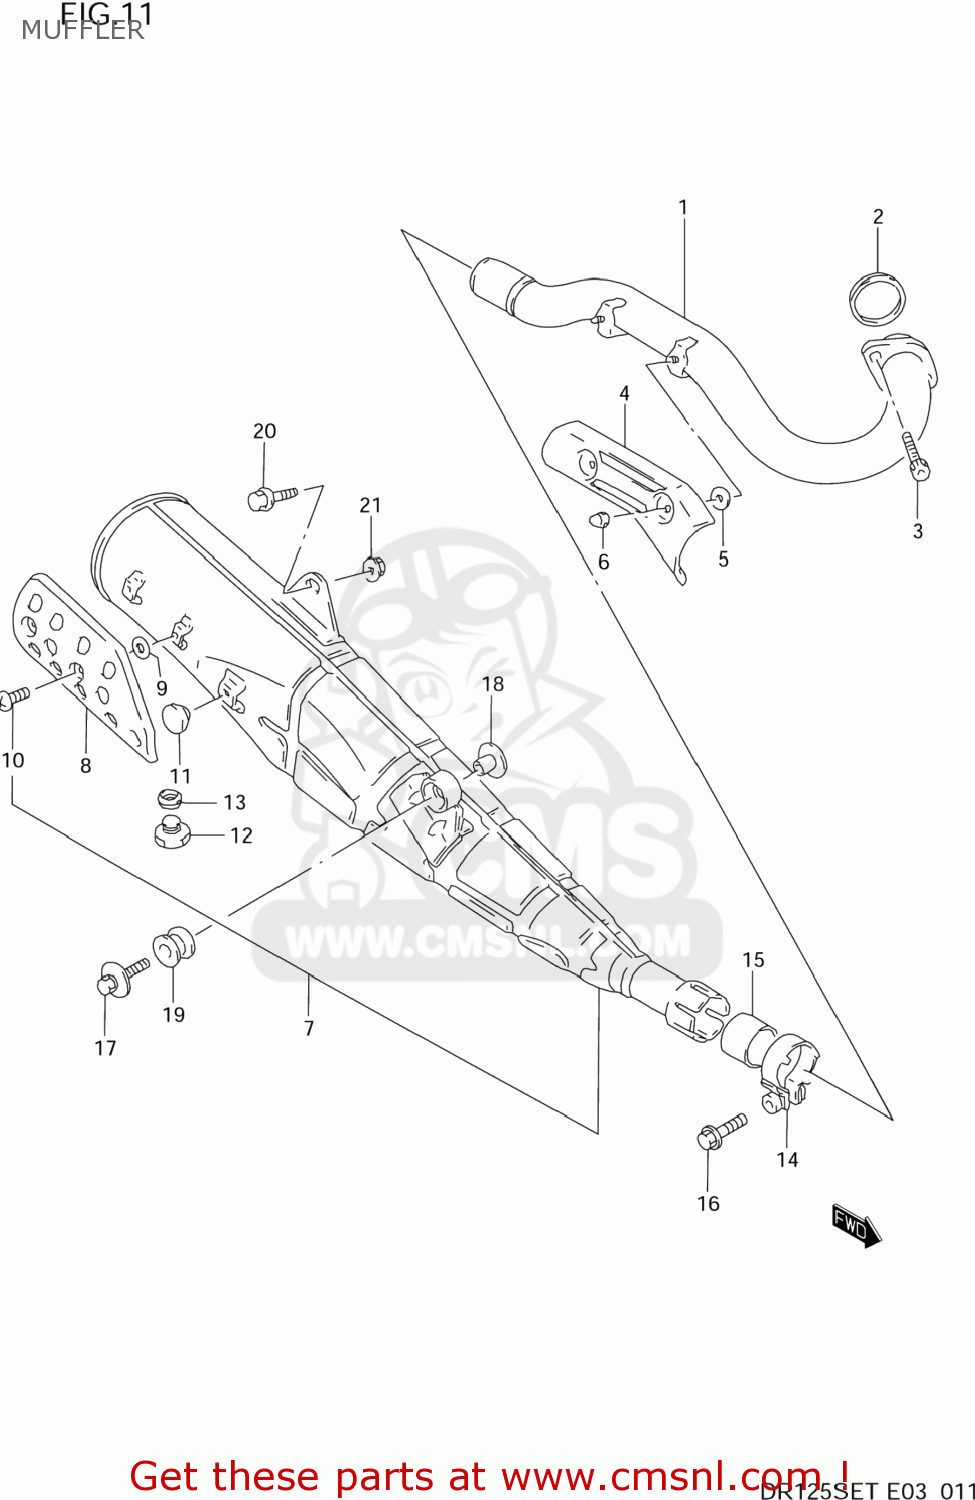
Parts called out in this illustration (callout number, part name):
1	PIPE COMP,EXHAUST
2	GASKET,EXHAUST (NAS)
3	BOLT
4	COVER,EXHAUST PIPE
5	GASKET (NAS)
6	NUT (6MM)
7	MUFFLER ASSY
8	COVER,MUFFLER
9	GASKET (NAS)
10	SCREW(6X10)
11	CUSHION
12	PLUG(12X9)
13	GASKET(12.1X16.2X3.7) (NAS)
14	CLAMP,MUFFLER CONNECTOR
15	GASKET,2ND MUFFLER (NAS)
16	BOLT
17	BOLT(8X35)
18	SPACER(8.6X12X17.5)
19	CUSHION
20	BOLT(8X35)
21	NUT
